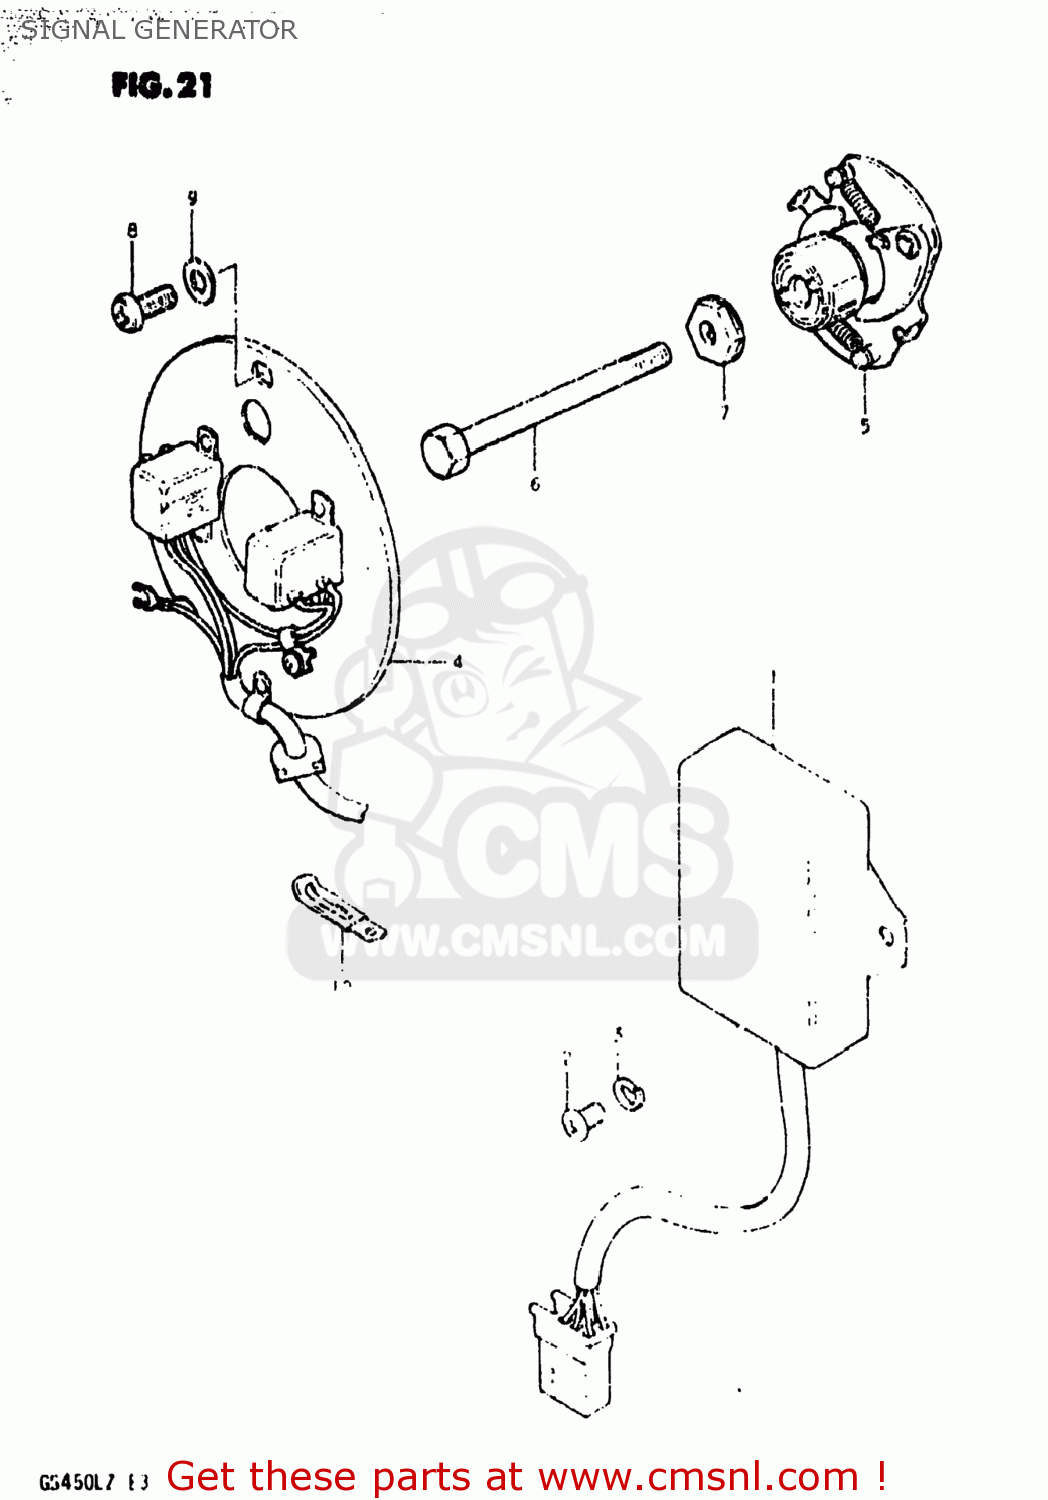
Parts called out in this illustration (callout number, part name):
1	CDI UNIT KOKUSAN
2	SCREW
3	LOCK WASHER
4	SIGNAL GENERATOR ASSEMBLY
5	GOVERNOR ASSEMBLY
6	BOLT 6X60
7	WASHER,CONTACT BREAKER
8	SCREW(5X12)
9	WASHER
10	CLAMP L:35
